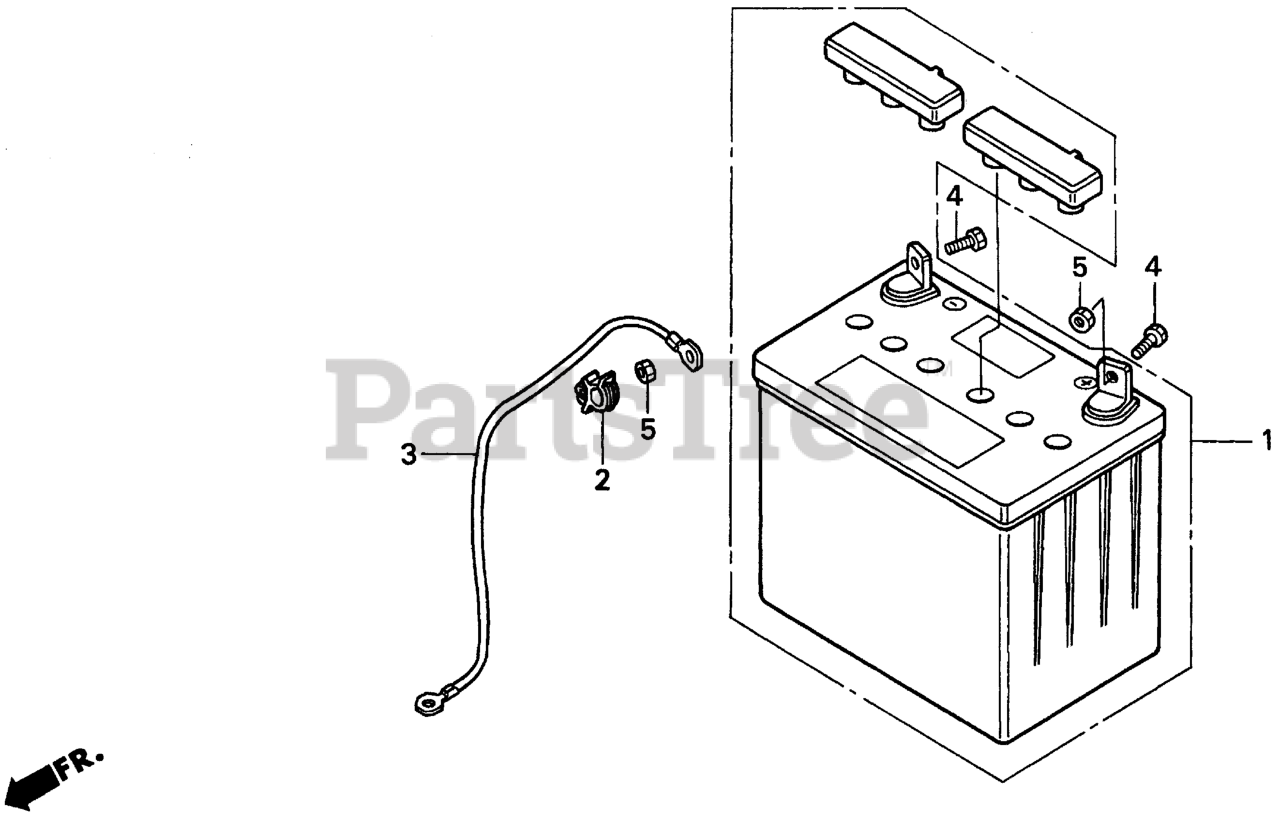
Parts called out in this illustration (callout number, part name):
1	BATTERY ASSY. (U1L-H)
1	BATTERY ASSY. (U1L)
2	CLIP, WIRE HARNESS
3	CABLE ASSY., GROUND
4	BOLT, BATTERY TERMINAL
5	NUT, BATTERY TERMINAL
